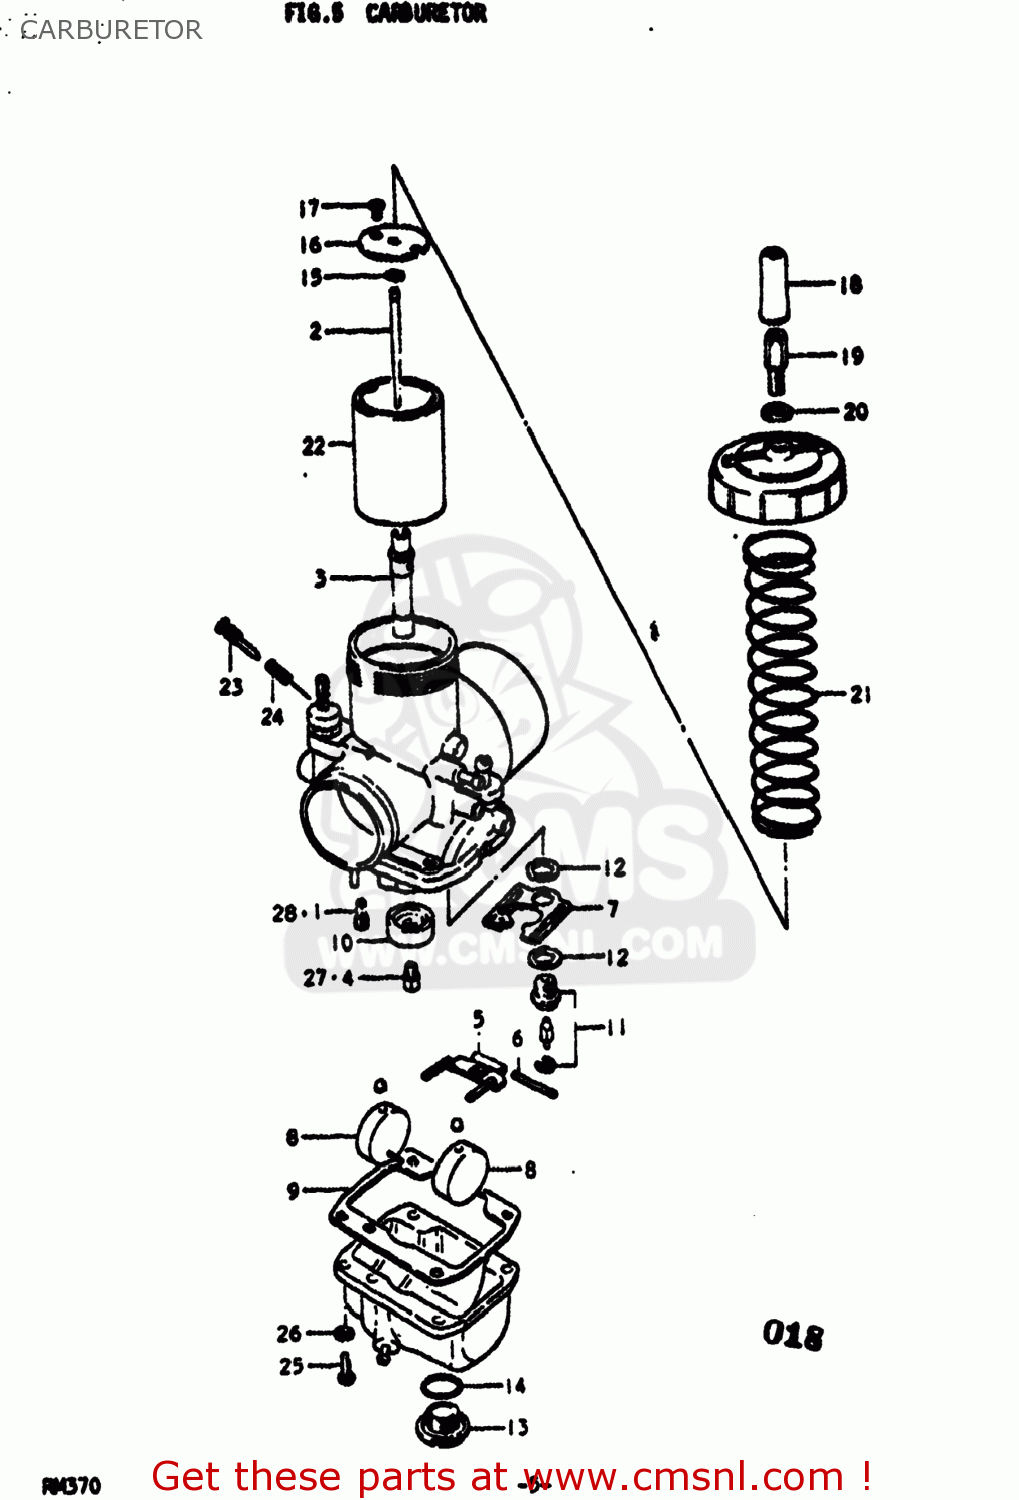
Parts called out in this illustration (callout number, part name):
0	CARBURETOR ASSEMBLY
1	JET,PILOT(50)
2	JET,NEEDLE(6FJ6-3)
3	JET,NEEDLE
4	JET
5	ARM,FLOAT
6	PIN,FLOAT
7	PLATE
8	FLOAT
9	GASKET,FLOAT CAHMBER (NAS)
10	RING
11	VALVE ASSEMBLY,NEEDLE
12	GASKET,MAIN JET HOLDER (NAS)
13	SCREW,GUIDE
14	O RING,DRAIN PLUG
15	CLIP
16	CLIP
17	SCREW
18	CAP,CABLE ADJUSTER
19	ADJUSTER,CABLE
20	NUT
21	SPRING
22	VALVE,THROTTLE
23	SCREW,PILOT AIR
24	SPRING
25	SCREW
26	LOCK WASHER
27	JET
28	JET,PILOT
